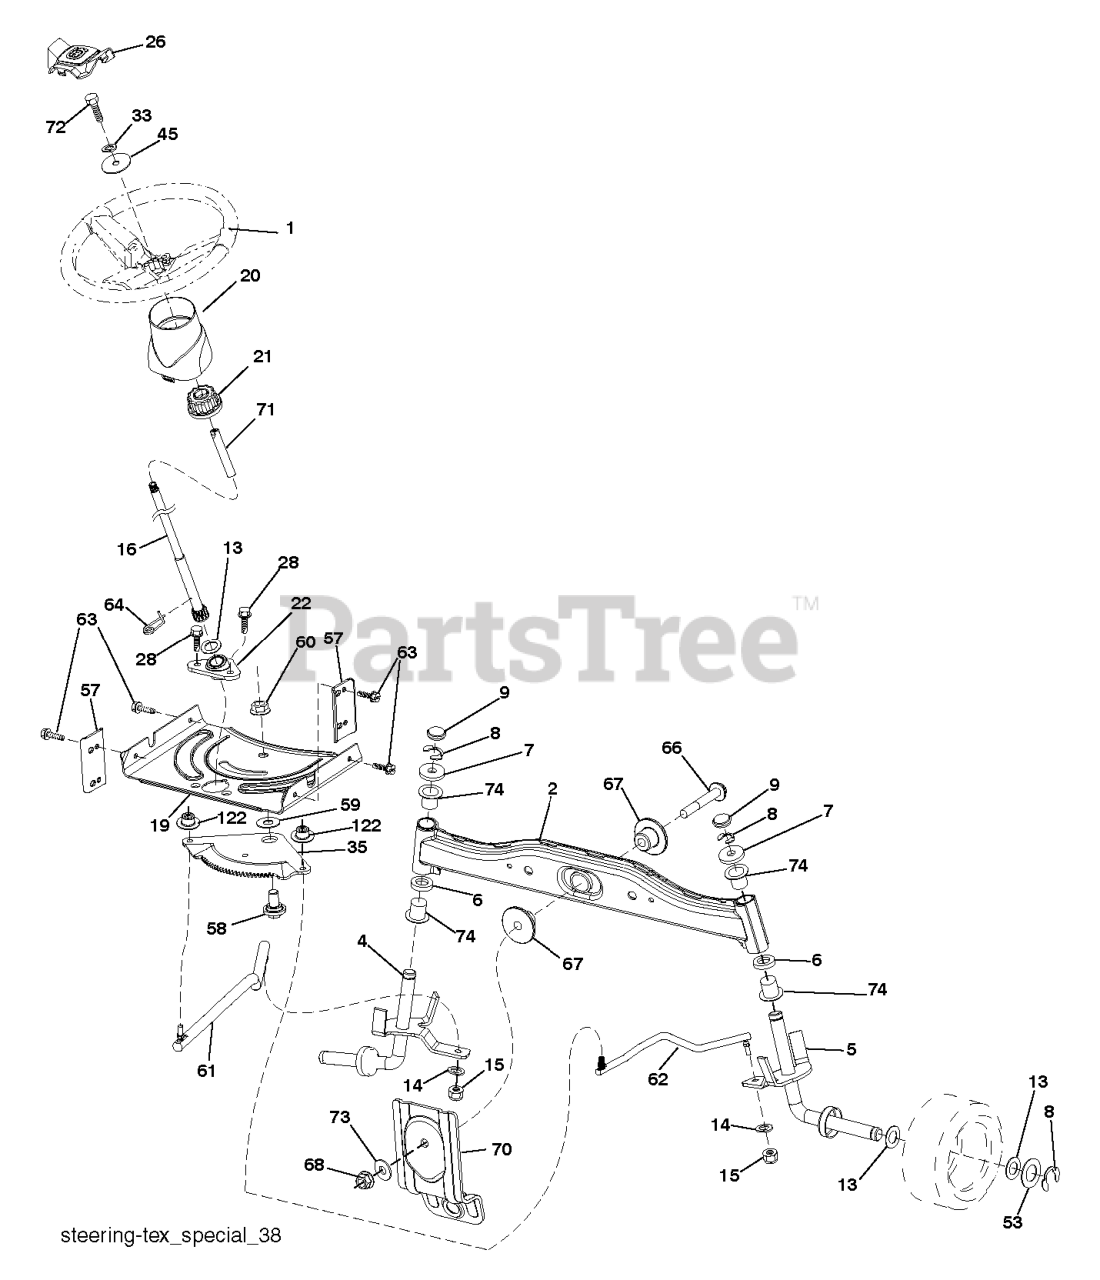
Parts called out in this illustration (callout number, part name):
1	RP WHEEL.STEER.HUSQ.PREM.OVMLD
2	AXLE HALF ASM-WELDED
4	SPINDLE.WELDED.LH.15"TEX
5	SPINDLE.WELDED.RH.15"T
6	THRUST WASHER
9	CAP.SPINDLE.BLACK
14	WASHER, LOCK 3/8
15	NUT CROWNLOCK 3/8-24
16	SHAFT STEERING
19	PLATE.STEER.DDL.NLT/NG
20	STEERING.BOOT.HUSQ.LT
21	ADAPTER, WHEEL STNG..
22	STEERING.SUPT.LOWER.
26	INSERT.CAP.WHL.STRG.HUSQ.PREM
28	SCREW, 3/8-16X3/4
33	WASHER.LOCK.HVY.HLCL.SPR.5/16
35	GEAR.SECTOR.PLATE.DDL.
45	WASHER.11/32
53	WASHER.HARDENED
57	BRACKET.UPSTOP.TEX
58	BOLT.SHOULDER.SECTOR.P
59	WASHER.THURST.SECTOR.S
60	NUT FLANGE LOCK 5/8-11
61	DRAGLINK.LH.BALLSTUD.D
62	DRAGLINK.RH.BALLSTUD.D
63	SCREW
64	RETAINER.CLIP.SPRING.S
66	BOLT HEX FGHD 7/16-14 X 3 SERR
67	BUSHING.PM.FRONT AXLE
68	NUT.LOCK.FLANGE.7/16
70	BRACKET.FRT.DECK.SUSP.RR.MT431
71	SHAFT EXTENSION STEERING
72	BOLT.FIN.HEX.5/16-18
73	WASHER.1.5X.505X.118
74	BRNG T
122	CAP.GEAR.SECTOR.TEX
